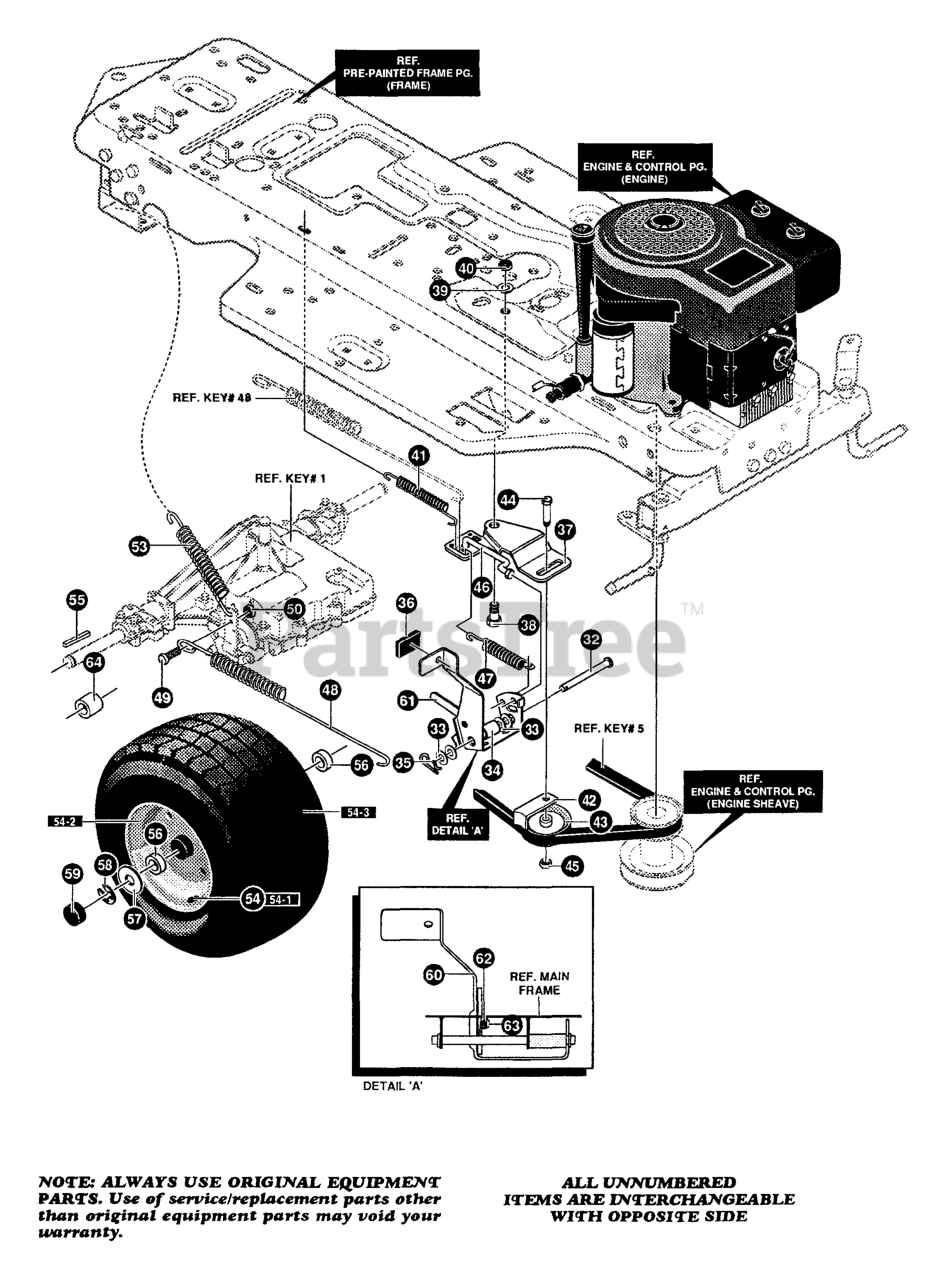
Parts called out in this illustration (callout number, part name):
32	PIN, CLEVIS
33	WASHER, FLAT 504 X .75 X .059
34	SPACER, SLEEVE
35	PIN, HAIR
36	PAD, CLUTCH/BRAKE PEDAL
37	IDLER ARM BRACKET
38	BOLT, .625 X .135
39	WASHER, FLAT .333 X .87 X .119
40	NUT, 5/16-18
41	SPRING, TENSION
42	RETAINER, BELT
43	PULLEY, IDLER
44	BOLT, 3/8-16 X 1.50
45	NUT, 3/8-16
46	CLUTCH ROD ASSEMBLY
47	SPRING, TENSION
48	SPRING, BRAKE
49	BOLT, .495 X .31
50	NUT, 5/16-18
53	SPRING
54	TIRE & RIM ASSEMBLY, 18 X 8.50-8
54-1	VALVE STEM
54-2	RIM, WHEEL
54-3	TIRE, 18 X 8.5-8
55	KEY, SQUARE
56	WASHER, FLAT .755 X 1.31 X .075
57	WASHER, FLAT .755 X 1.53 X .07
58	RING, RETEX
59	HUB CAP
60	PEDAL, BRAKE, CLUTCH
61	LEVER, PARK BRAKE
62	SPRING, PARKING BRAKE
63	RIVET
64	SPACER, .87 X 1.12
